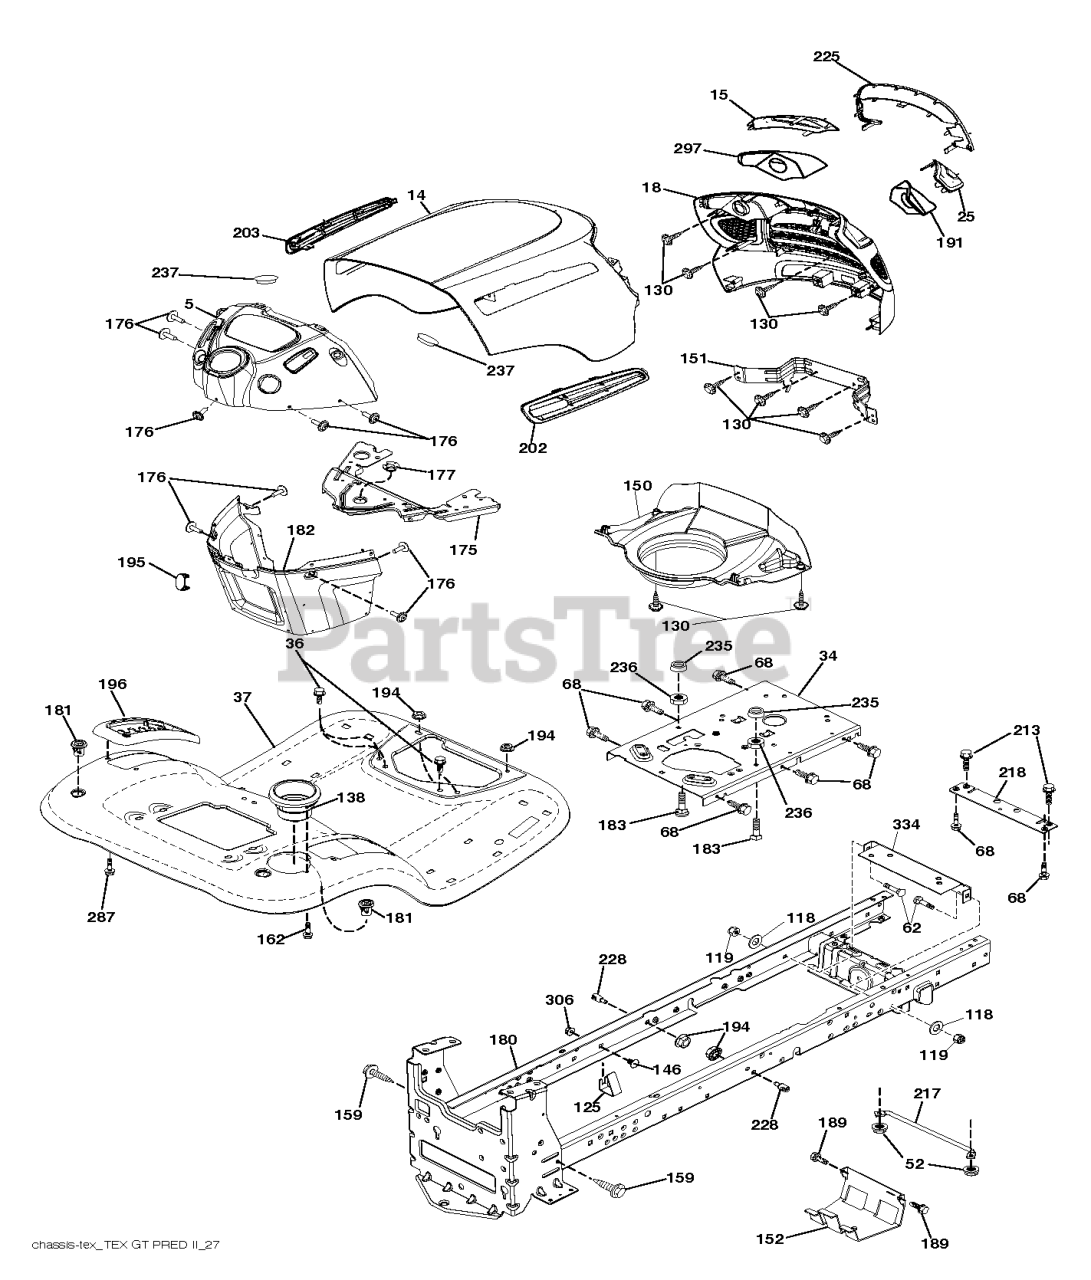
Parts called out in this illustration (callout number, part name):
5	DASH.UPPER.PREDATOR.M/C.BLACK
14	HOOD.PNT.PREDATOR.YT/GT.BLACK
15	LENS.MCCULLOCH.GT.LH
18	GRILLE.PREDGT2.GEN
25	LENS.MCCULLOCH.GT.RH
34	PLATE.ENGINE.WELDED.CHASSIS
36	SCREW 5/16"
37	FENDER.TLT.W/CPH.428
52	Locknut, Hex w/Insert 5/16-18 Unc
62	Bolt, Carriage 3/8-16 UNC x 1 Gr. 5 (AYP part number)
68	SCR 5/16-18 X 1/2 SELFTAP ZN
118	Washer 13/32 x 1-3/16 x 12 Gauge (AYP part number)
119	Nut, Hex, Lock Hex w/wsh 3/8-16
125	CLIP.FUEL.LINE
130	SCREW.#10 X 0.750.BOS (2 2)
138	CUPHOLDER.TL.TEX.BLACK
146	BOLT.RDHD.SHT.SQNK.3/8-16X5/8
150	AIR DUCT.HOOD.PRED YT/GT(2 2)
151	BRACKET.PIVOT.PREDATOR
152	SHIELD.BROWNING.W/TEX
159	SCREW, 3/8-16X3/4
162	Screw, Hex Wsh Hi-Lo 1/4-1/2 (AYP part number)
175	PLATE.PNT.CROSSMEMBER.HUSQ/PRE
176	SCREW.#10-24X5/8.RN.QU
177	BUSHING STEERING
180	CHASSIS
181	FEND/FTRST.PCH.CPH.NFW
182	DASH LOWER.HUSQ.PRED NO CRUISE
183	BOLT.5/16-18X1-1/4 FULL THD
189	SCREW
191	REFLECTOR.MCCULLOCH.GT.RH
194	NUT LOCK HEX FLANGE 5/16-18
195	PLUG.HOLE.DASH.LOWER.12V.BLK
196	CONSOLE.ASM.DECKLFT.BL/YBT.TLT
202	VENT.SIDE.HOOD.RH.PREDATOR.BLK
203	VENT.SIDE.HOOD.LH.PREDATOR.BLK
213	Bolt, Hex Head 5/16-18 UNC x 3/4 (AYP part number)
217	ROD.PIVOT.HOOD
218	X-PIECE.HOOD.STOP.NON/
225	TRIM.RING.MCCULLOCH.GT
228	STUD.FASTNER.W/ANTI-ROTATE
235	SPACER FENDER
236	NUT.CENTERLOCK.5/16-
237	PLUG.MOUNT.CARGO.BLK
287	SCREW 1/4X20
297	REFLECTOR.MCCULLOCH.GT.LH
306	NUT LOCK FLG 3/8-16 UNC
334	BRACKET.ENGINE
